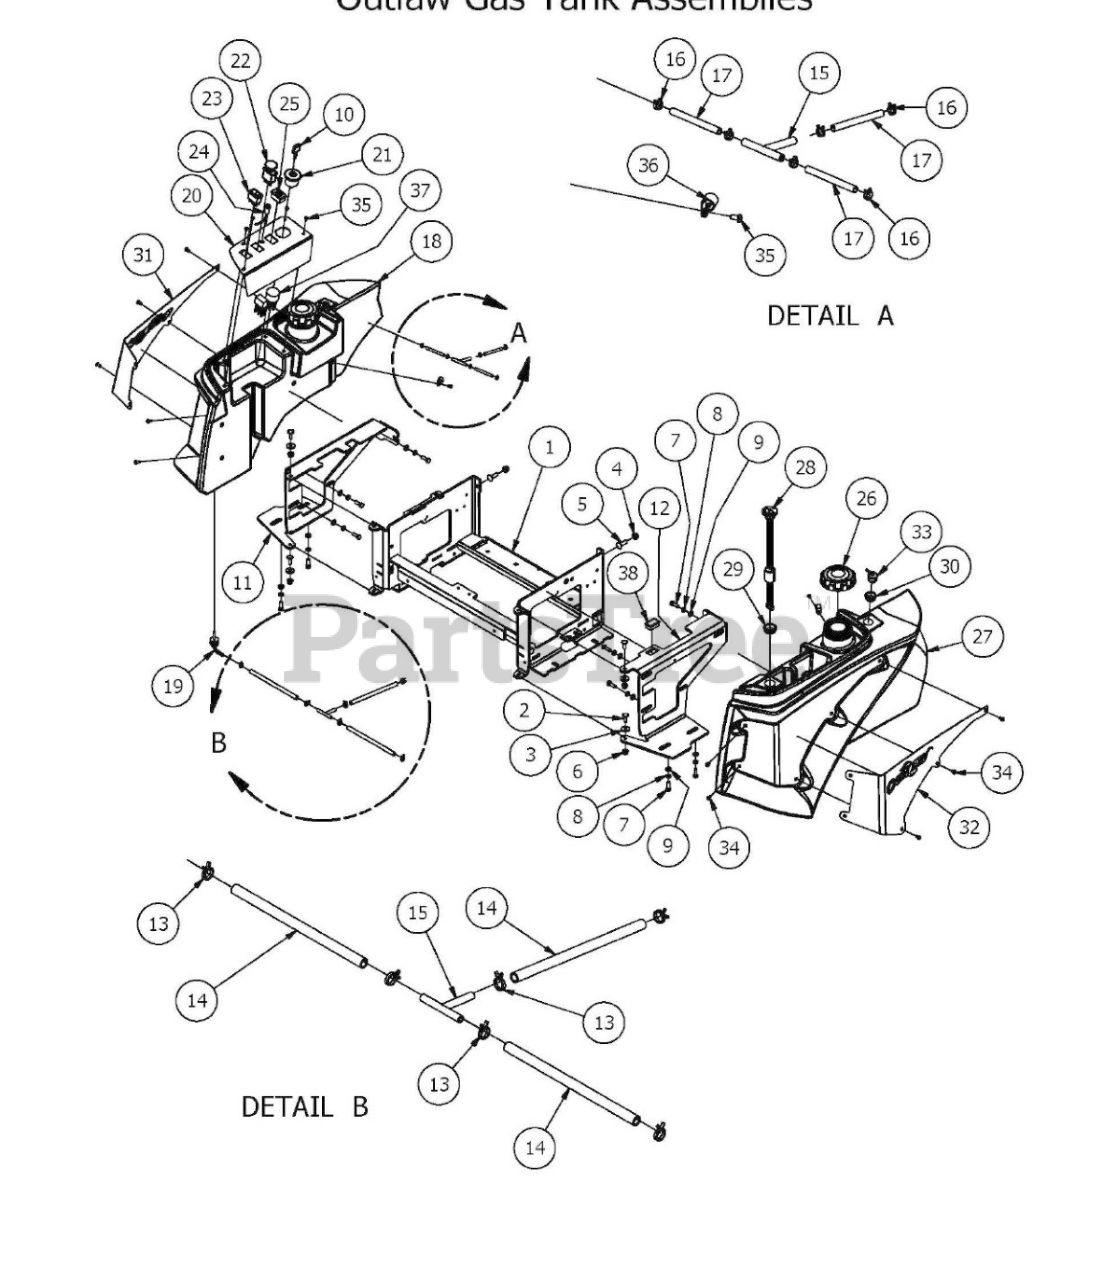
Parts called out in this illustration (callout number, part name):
1	2017 Outlaw Seat Bracket
2	5/16-18 x 1 Carriage Bolts Zinc
3	.360 ID Plastic Washer
4	3/8" Nylock Flange Nut
5	3/8" x 1 1/4" Carriage Bolt
6	5/16-18 Nylon Insert Flange Nut Zinc Orange Nylon
7	5/16" x 1" Bolt
8	5/16" Lock Washer
9	5/16" Flat Washer
10	Ignition Key
11	Outlaw 2015 Tank Support (Right)
12	Outlaw 2016 Tank Support (Left)
13	1/4 Fuel Hose Clamp
14	1/4" Fuel Line Hose
15	fuel line T
16	3/16 Vinyl Clamp
17	1/4" Vinyl Tubing
18	Outlaw 2015 Fuel Tank (Right)
19	Fuel Tank Hose Nipple w/Filter
20	Analog Control Panel Outlaw
21	Ignition Switch
22	PTO Switch
23	Rocker Deck Lift Switch
25	Tachometer
26	Fuel Cap (Kelch)
27	Outlaw 2015 Fuel Tank (Left)
28	Fuel Gauge w/Grommet
29	Grommet for Fuel Gauge
30	ROV Grommet
31	Outlaw Tank Panel (Right)
32	Outlaw Tank Panel (Left)
33	Rollover Valve - Black
34	1/4" x 1/2" BS C/S 18-8 SS
35	10-32 x 3/8" Button Socket Head Bolt
36	3/8 Cable Clamp-Black Nylon
37	Wiring Harness
38	Light Plug
